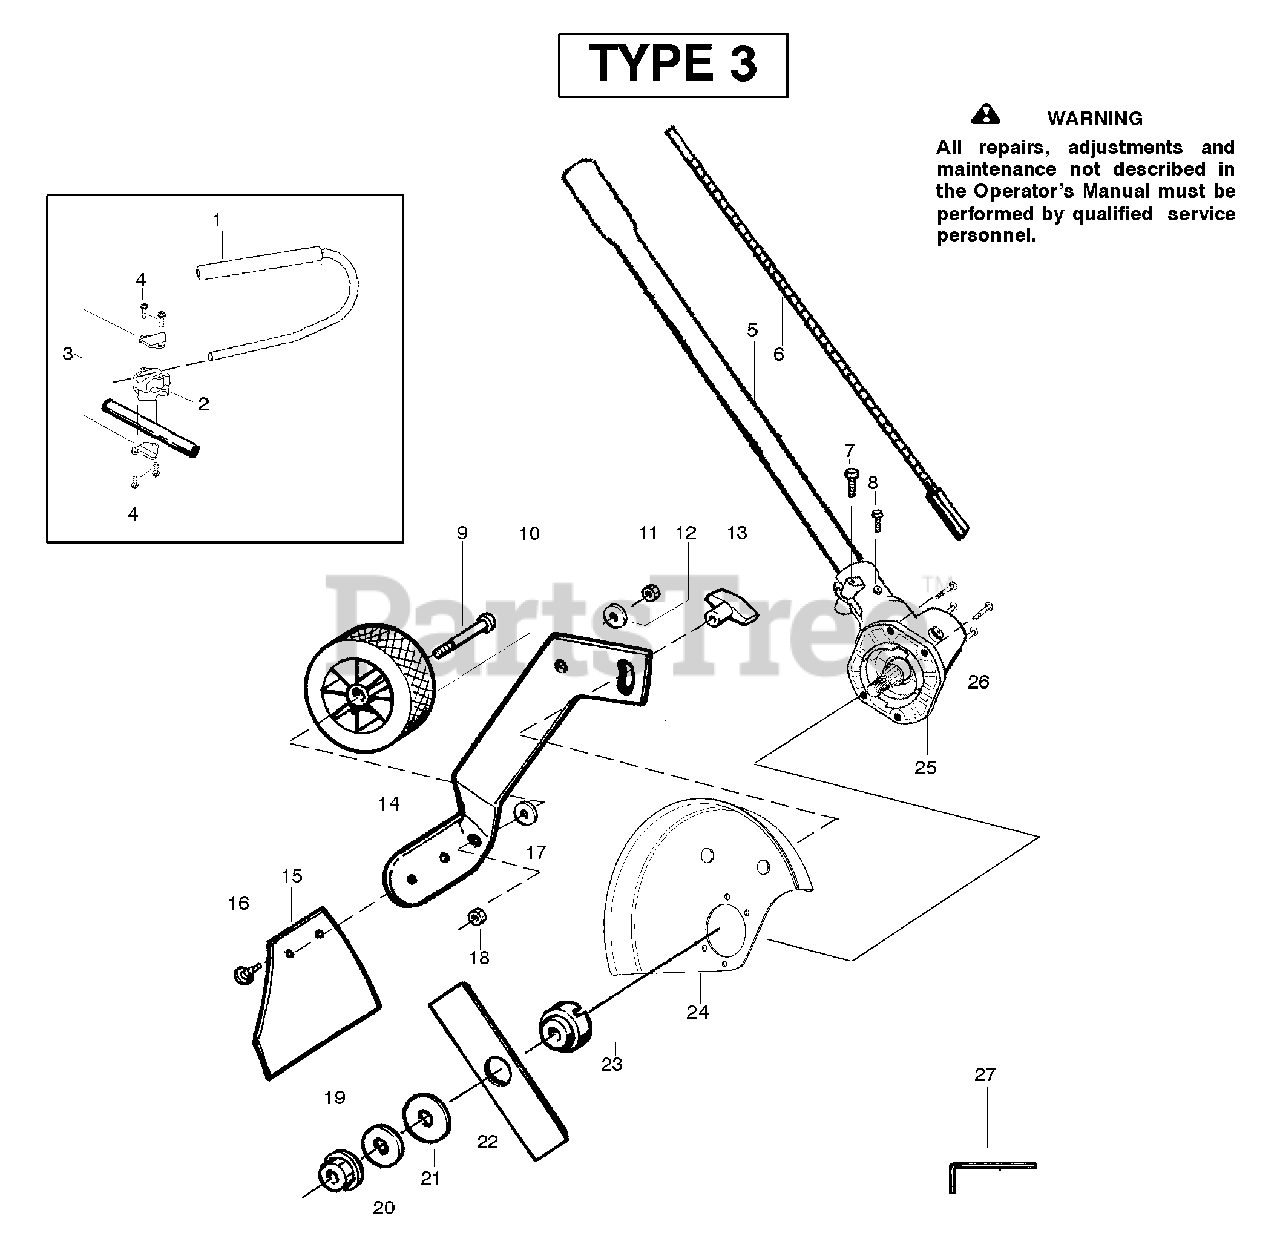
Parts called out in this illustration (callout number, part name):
1	Kit-Handlebar
2	Clamp-Handlebar (7/8")
2	Clamp-Handlebar ( 1")
3	Bracket-Clamp
5	Assy.-Driveshaft
6	Flexshaft-Split boom
8	Screw-Alignment
9	Bolt-Shoulder Axle
10	Wheel-4"
14	Bracket-Adj. Wheel
15	Kit-Mud Flap
16	Fastener-Mud Flap
19	Nut-Flange
20	Washer-Belleville
21	Washer-Flat
22	Accy-7.5" Blade
24	Kit-Edger Guard
25	Kit-Gearbox
27	Wrench-Hex (5/32")
